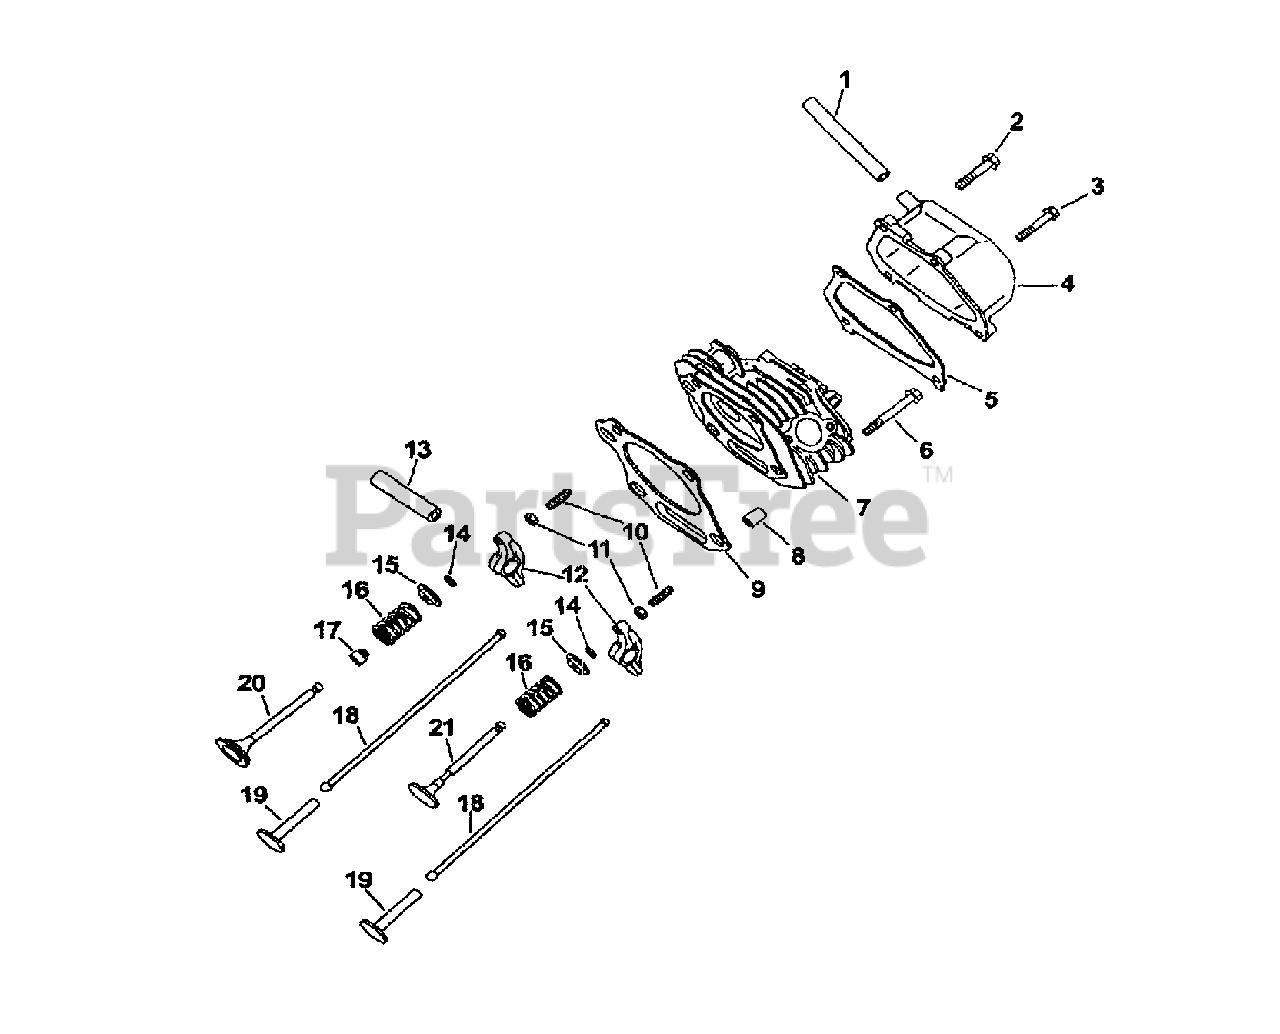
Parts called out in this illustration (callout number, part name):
1	Hose, Breather
2	Screw, Valve Cover
3	Screw, Valve Cover
5	Gasket, Valve Cover
6	Screw, Cylinder
7	Head, Cylinder
10	Screw, Valve Adj.
13	Shaft, Rocker Arm
14	Keeper, Valve
15	Cap, Valve Spring
16	Spring, Valve
17	Seal, Vaqlve Stem
20	Valve, Intake
21	Valve, Exhaust
